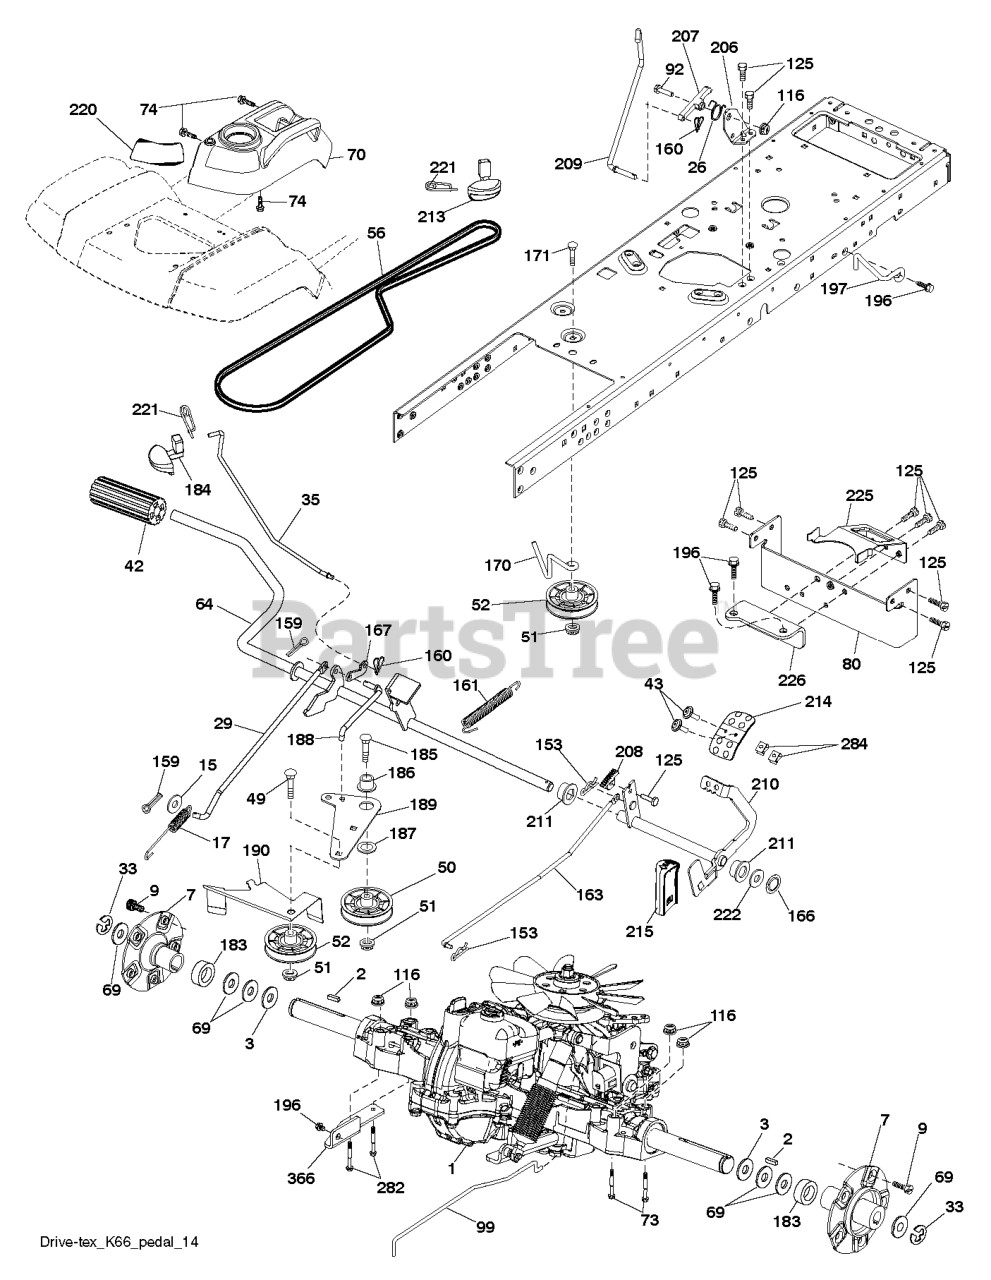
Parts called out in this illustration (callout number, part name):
2	KEY 1/4 X 2.5
7	HUB.ASM.WHEEL.REAR.23"TEX
9	HUB BOLT
15	WASHER
17	SPRING.BRAKE.K46
26	SPRING.RETURN.CRUISE
29	ROD.BRAKE.K66
33	E RING HYT
35	ROD.BRAKE.PARTK.HUSQ.TEX
42	PEDAL COVER T
43	SCREW.MACHINE.CR.1/4-20
50	IDLER.FLAT.910.OFFSET
51	NUT LOCK FLG 3/8-16 UNC
52	IDLER.V-GROOVE.910.OFFSET
56	V-BELT.GROUND.DRIVE.
64	SHAFT.ASM.PEDAL.BRK.CNTR
70	CONSOLE.ASM.RH.GT.FC.HUSQ
73	BOLT HEX 5/16-18 GR 5
74	SCREW.HI-LO.CONSOLE
80	STRAP.TORQUE.K66
92	BOLT
99	ROD.SPRING.BYPASS.K66.GT.Z
116	NUT LOCK HEX FLANGE 5/16-18
125	SCREW
153	RETAINER M
159	COTTER PIN
160	RETAINER CLIP
161	SPRING, RETURN LT
163	ROD.PEDAL.CONTROL
166	NUT.PUSH.625
167	LATCH.BRAKE.SPRING
170	KEEPER.CENTER SPAN.1.688
171	BOLT
183	SPACER.AXLE.HG.TEX
184	RB HANDLE.PARKG.BRK.HUS/PRED
186	SPACER.RETAINER
187	WASHER 12/32X2X10GA
188	RP.LINK.CLUTCH.GROUND.DRIVE
189	BELLCRANK.GROUND.DRIVE.TEX.
190	KEEPER.BELLCRANK.DRIVE
196	SCREW 3/8-16X1
197	BRKT.ANIT-ROTATION.CLUTCH
206	BRACKET.MOUNT.CRUISE.LATCH
207	LATCH.CONTROL.CRUISE
208	GEAR.SECTOR.CONTROL.CR
209	ROD.CONTROL.CRUISE.GT.
210	ROCKER.ASM.PEDAL.CONTR
211	BEARING.NYLON
213	KNOB.CONTROL.CRUSIE.HU
214	PEDAL.FORWARD.HUSQVARNA.DEALER
215	PEDAL.REVERSE.TEX.GT.4
220	REFLECTOR.RH.TEX GT
221	RETAINER.SPRING.CLIP.H
222	WASHER 21/32 X 1-1/4 X 10 GA.
225	KEEPER.BELT.TRANSAXLE.K66
226	BRACKET.MOUNT.TORQUE.K66.TG
282	BOLT HEX FLGHD 5/16-18X3 GR. 5
284	NUT.U-CHNL.1/4-20.550DP.350PNL
366	BRACKET.REINFORCEMENT
